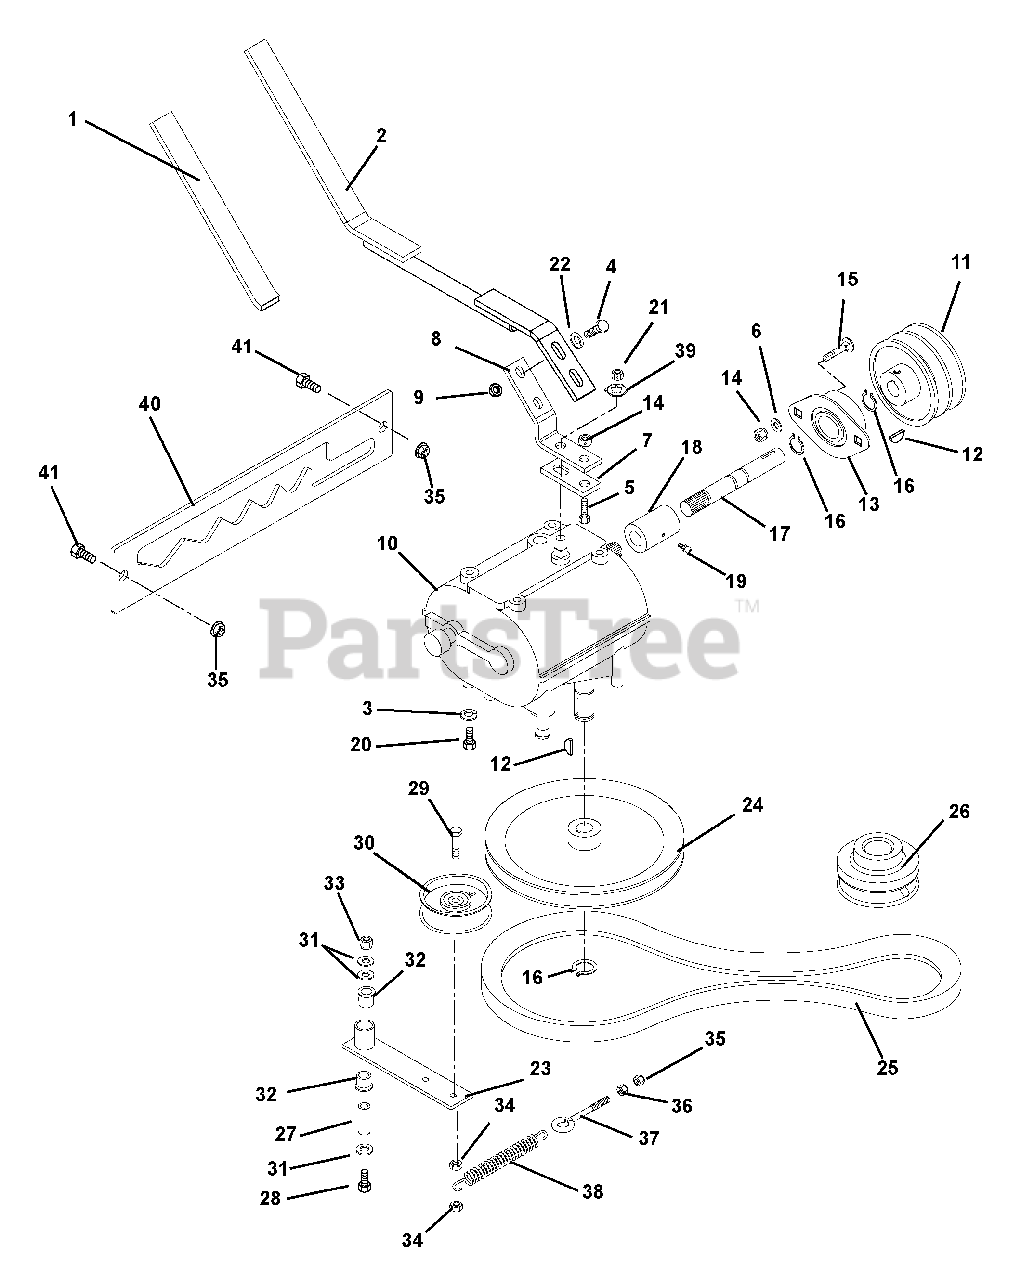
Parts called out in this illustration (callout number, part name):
1	GRIP
2	WMT - SHIFT LEVER
3	@WSHR-LK .31X.078 REG YWZC
4	@BLT-HEX .31-18X1.00 GR5 YWZC
5	@BLT-HEX .25-20X1.00 GR5 YWZC
6	@WSHR-FL-STL.250X.56X.049 YWZC
7	PLATE, SHIFT
8	BRACKET, SHIFT LEVER
9	@NUT-LK-TOP-FLG .31-18 YWZC
10	TRANSMISSION
11	SHEAVE-DRIVE 3.25 OD X .625 ID
12	KEY-WDRF .19X.75 HRD #9
13	BRG-FLG .625X1.875X.797
14	@NUT-LK-NYL .250-20 YWZC
15	@BLT-RDHDSQNK .25-20X.75 G5YZ
16	RG-RTNG-EXT .579X.035
17	SHAFT, HALF
18	COUPLER
19	FTG-LUBE .25-28X.256 YWZC
20	@BLT-HEX .31-18X.75 GR5 YWZC
21	NUT-LK-CTR .375-24 YWZC
22	@WSHR-FL-STL.344X.688X.065YWZC
23	WLDMT,GROUND DRIVE IDLER
24	PLY-V 7.50X.626
25	V-BELT, 4L-COGGED
26	SHEAVE - CLUTCH
27	BUSH.,S.560X.745X2.04 ST
28	@BLT-HEX .50-13X3.25 GR5 YWZC
29	@BLT-HEX .38-16X2.00 GR5 YWZC
30	IDLER-PLY FLAT 3.25 X .38 X1.0
31	@WSHR-FL-STL.531X1.06X.095YWZC
32	BSHG-FLG .762X1.0X.580X1.48 NY
33	@NUT-LK-NYL .50-13 YWZC
34	@NUT-LK-CTR-JAM .375-16 YWZC
35	@NUT-LK-NYL .38-16 YWZC
36	@NUT-HEX .38-16 YWZC
37	BLT-EYE .375-16X2.50 YWZC
38	SPRING, EXT
39	WSHR-LK .375X.130 YWZC
40	PLATE - SHIFT LEVER DETENT
41	@BLT-HEX .38-16X1.00 GR5 YWZC
